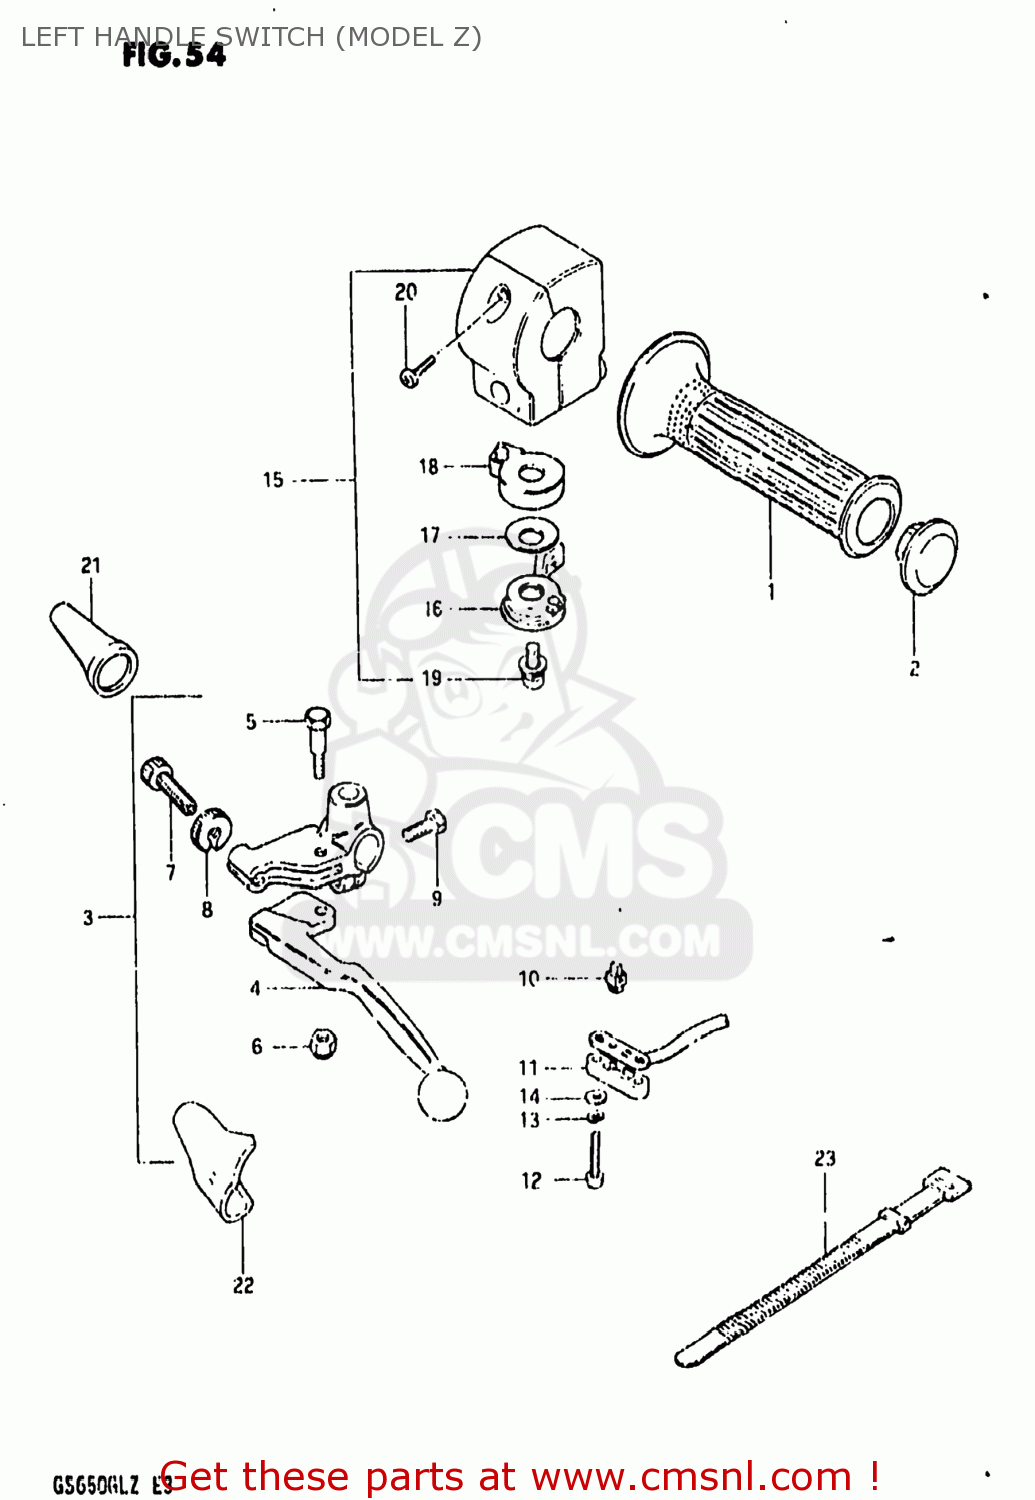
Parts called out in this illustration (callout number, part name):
1	GRIP,LEFT
2	CAP,GRIP END
3	LEVER ASSEMBLY
4	LEVER,CLUTCH
5	BOLT,LEVER
6	NUT 6MM
7	ADJUSTER,CABLE
8	NUT,CABLE ADJUSTER
9	BOLT,CLUTCH LEVER HOLDER
10	CONTACT,SWITCH
11	COVER,FR BK TERMINAL BASE
12	SCREW
13	LOCK WASHER
14	WASHER
15	SWITCH ASSEMBLY,HANDLE,LEFT
16	LEVER,STARTER
17	WASHER,ADJUSTER
18	BODY,CHOCK
19	SCREW,CHOKE LE
20	SCREW
21	COVER,CLUTCH LEVER
22	BOOT,CLUTCH CABLE
23	CLAMP(L:120)
